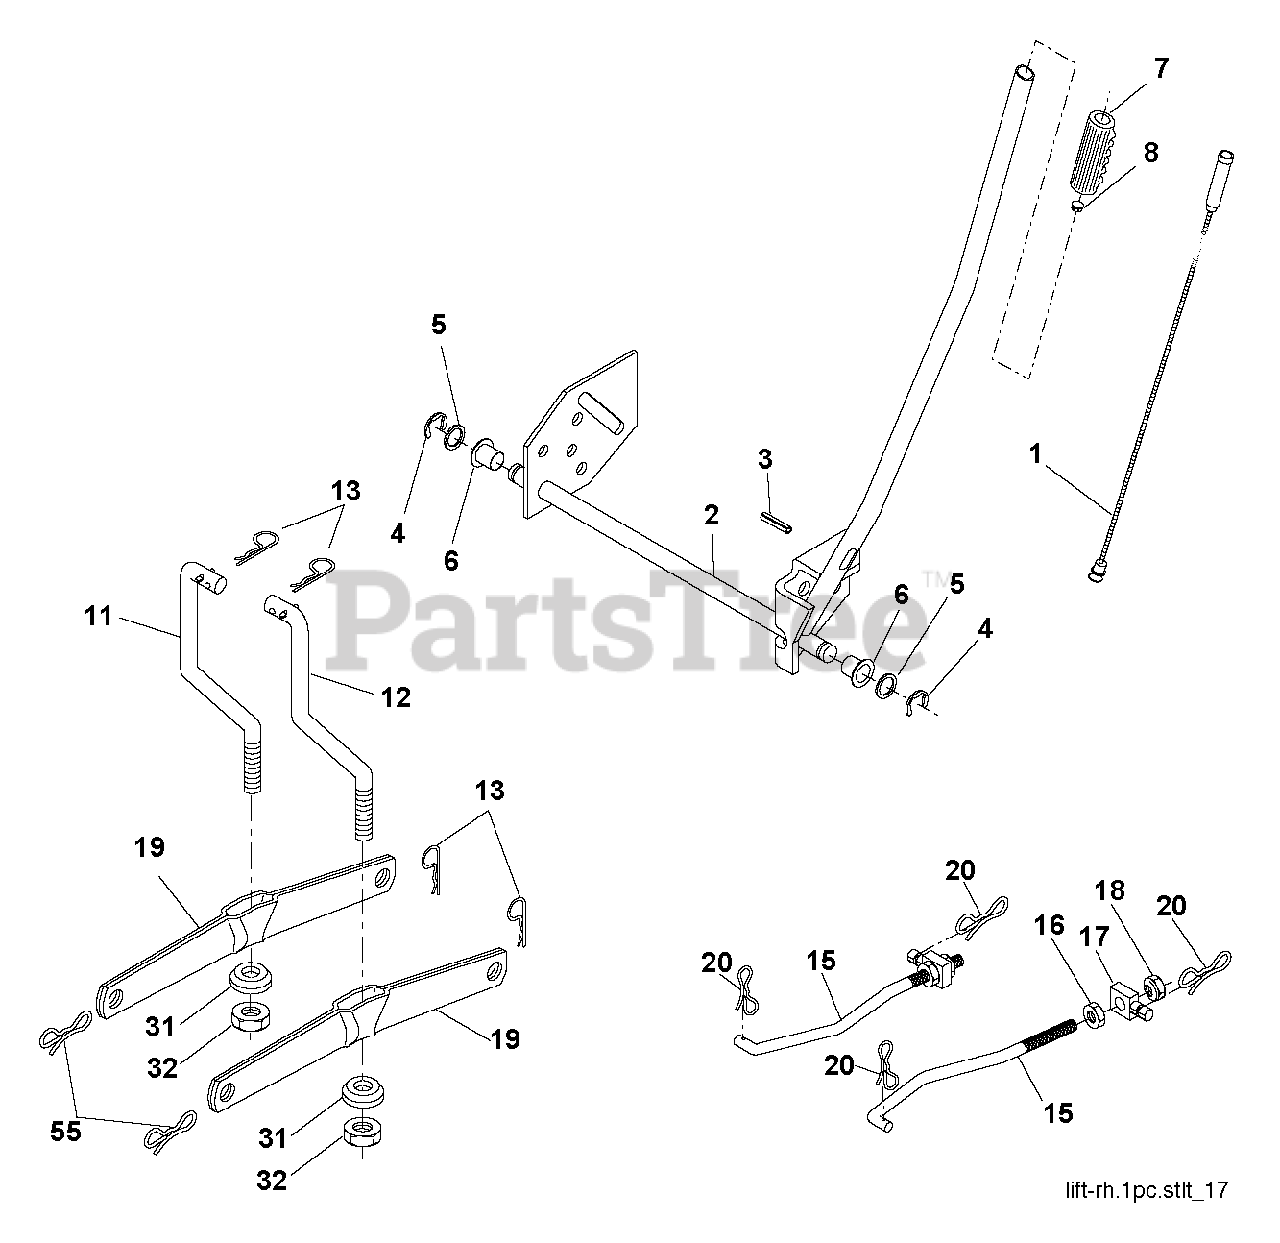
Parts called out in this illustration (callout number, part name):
1	PLUNGER.ASM.LIFT.LVR.BLK.17.32
2	SHAFT ASM R HANDLE
3	PIN GROOVE.
4	RETAINING RING LT
6	BEARING.NYLON
7	GRIP
8	PLUNGER BUT KIT
11	LINK LIFT LH
12	Lift Link Assembly, RH
13	RETAINER-SPRNG RB
15	LINK.SUSPENSION.FRONT
16	NUT.HEX.JAM.1/2-13
17	TRUNNION
18	NUT.LK.W/WSH.1/2.
19	ARM.REAR.SUSPENSION
20	PIN.COTTER.7/16.BOW TI.
31	BEARING.PIVOT.LIFT
32	NUT CROWNLOCK 3/8-24
55	PIN.COTTER.5/16.BOW TI
